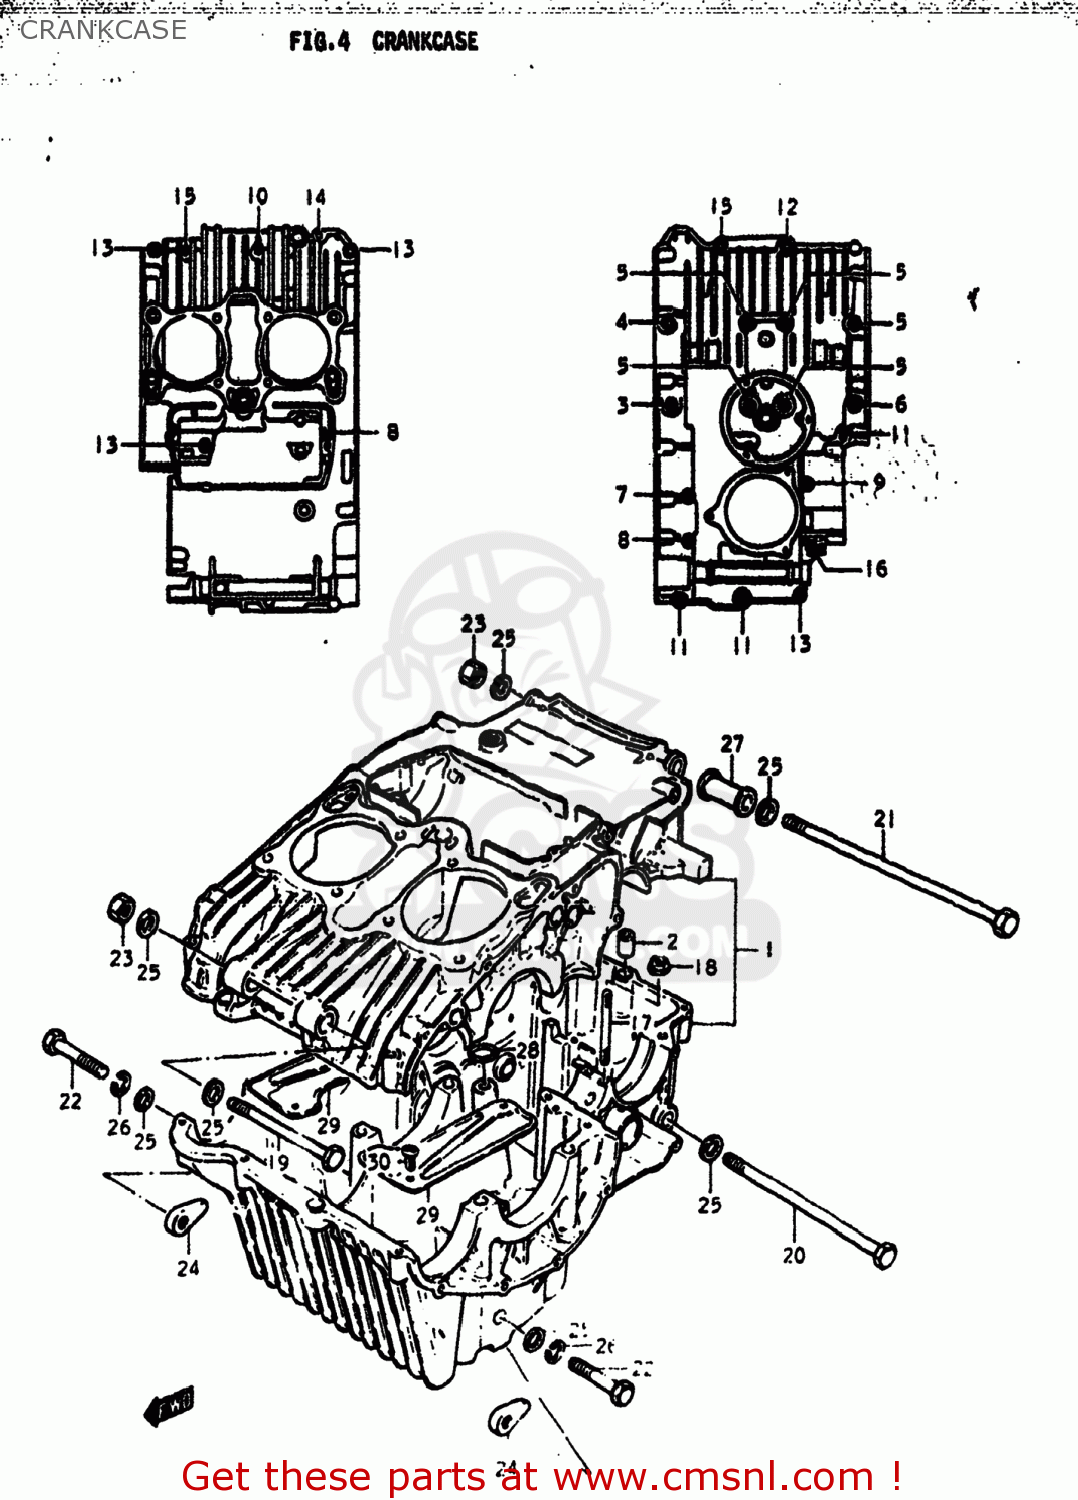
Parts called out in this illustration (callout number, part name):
1	CRANKCASE SET
2	PIN
3	BOLT
4	BOLT (8X95)
5	BOLT 8X90
6	BOLT
7	BOLT
8	BOLT (6X90)
9	BOLT (6X70)
10	BOLT 6X65
11	BOLT (6X60)
12	BOLT,UNDER
13	BOLT
14	BOLT 6X35
15	BOLT
16	BOLT (8X45)
17	STUD BOLT
18	NUT
19	BOLT
20	BOLT 10X160
21	BOLT 10X265
22	BOLT
23	NUT
24	NUT
25	WASHER
26	LOCK WASHER
27	SPACER,ENGINE MOUNT
28	O-RING
29	O-RING
30	SCREW
